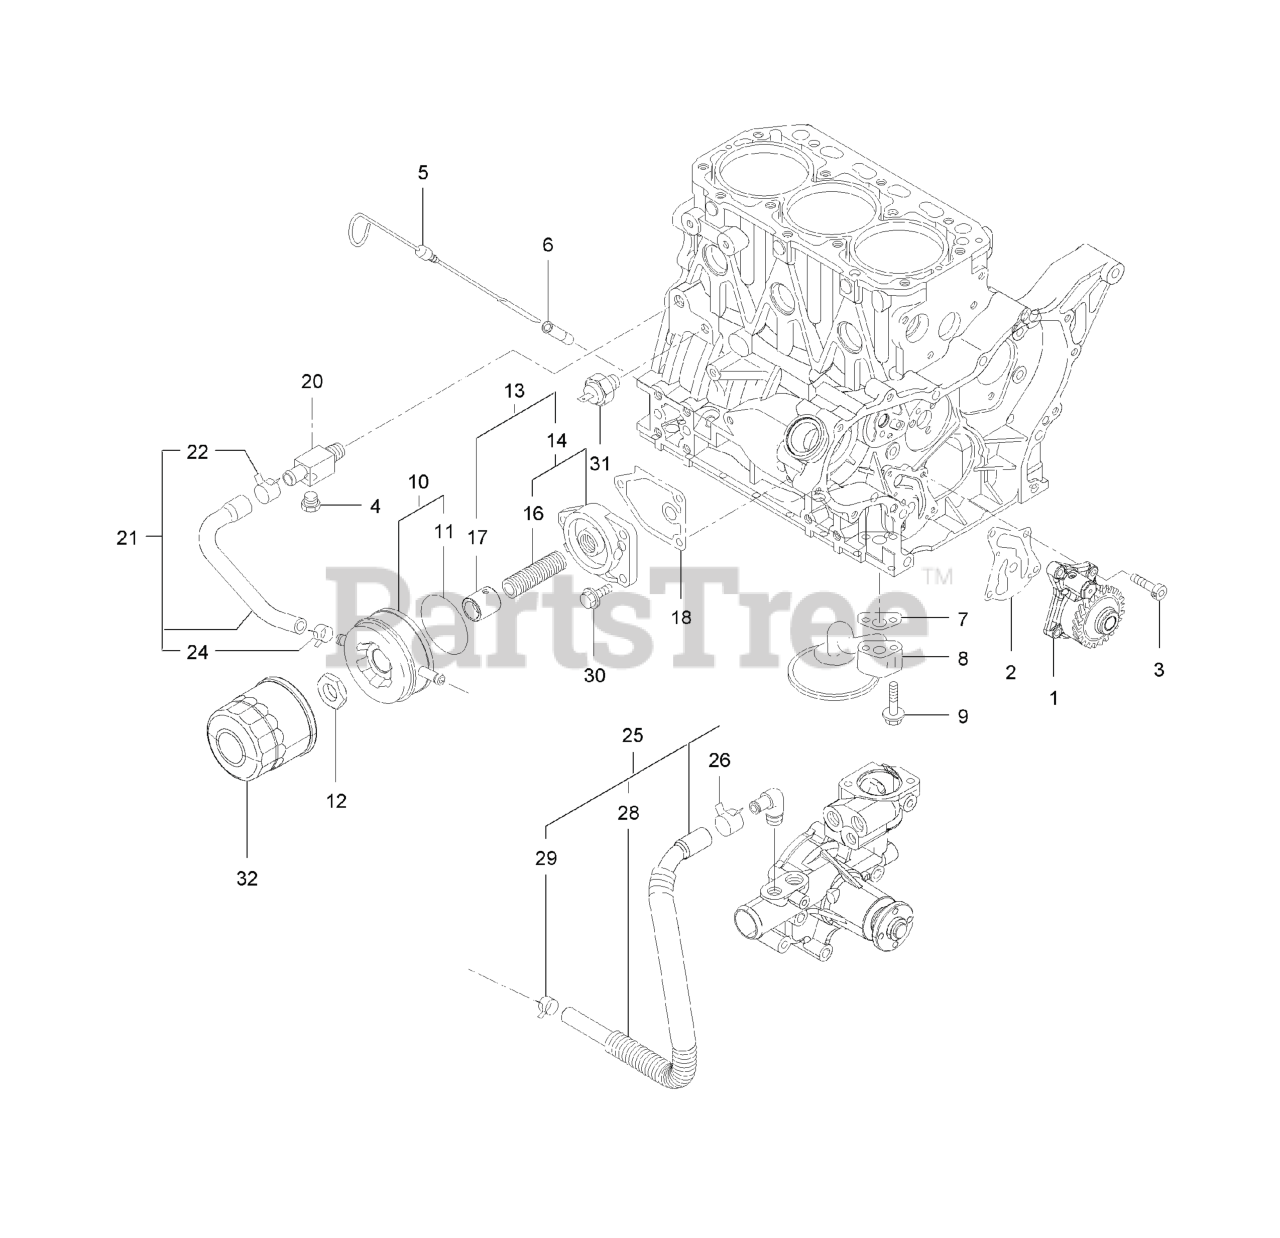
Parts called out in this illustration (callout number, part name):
1	OIL PUMP ASM
4	PLUG-DRAIN
5	DIPSTICK
6	GUIDE-DIPSTICK
8	PIPE ASM-OIL INLET
10	COOLER ASM-OIL
11	PACKING-OIL COOLER
13	BRACKET ASM-LO FILT
14	BRACKET ASM
17	COLLAR-OIL COOLER
21	PIPE ASM
24	CLAMP-HOSE
25	PIPE ASM
29	CLAMP-HOSE
31	SWITCH-OIL
32	FILTER-ENGINE
